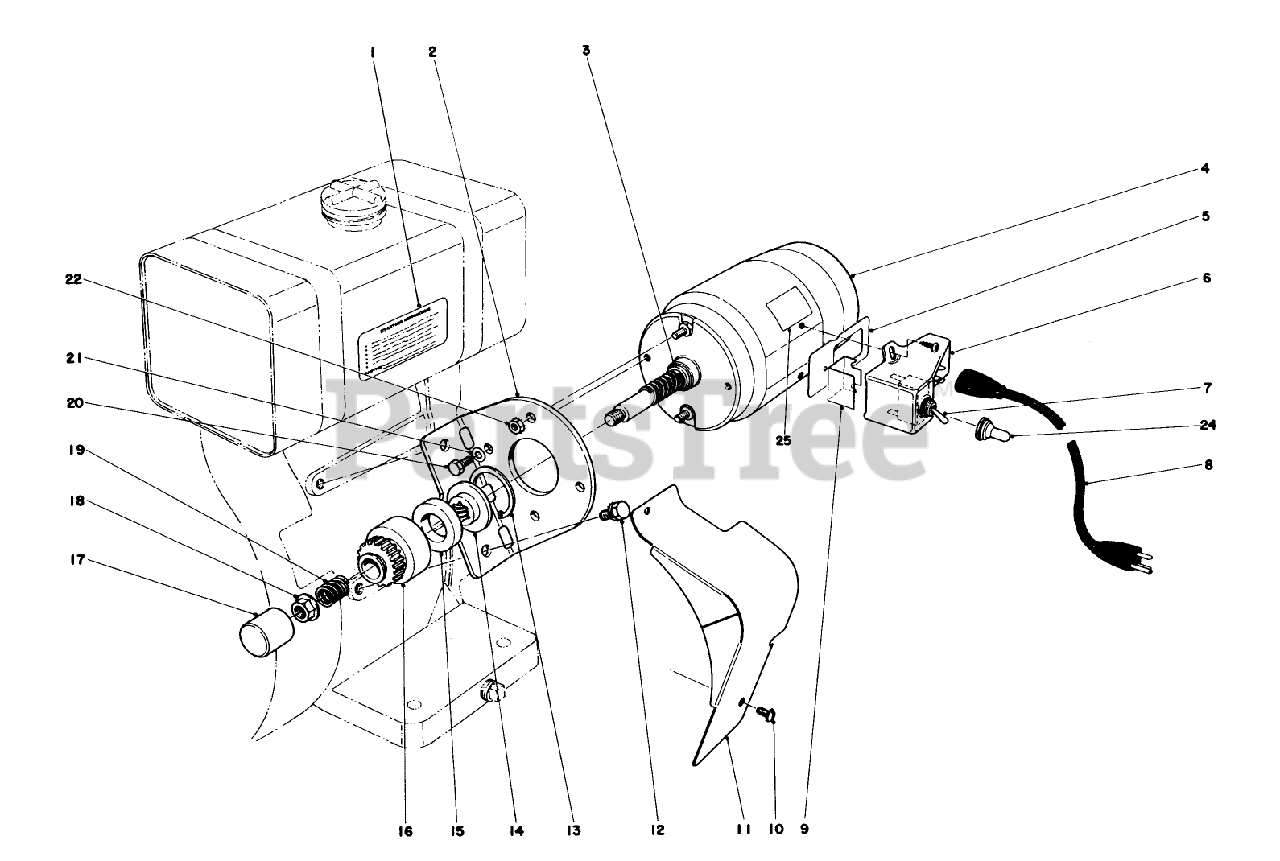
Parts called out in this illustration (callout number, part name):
2	Mounting Bracket
4	Starter Motor
7	SWITCH & BOOT ASM
8	TECUMSEH 7641
11	BRIGGS 280265
12	5/16-18X3/4 HX HD SEM
17	WEATHER CAP
18	NUT-HHF
20	SLOT HD SCREW
21	WASHER-LOCK, INT
22	NUT-KEPS
24	BOOT-SWITCH
25	Decal
